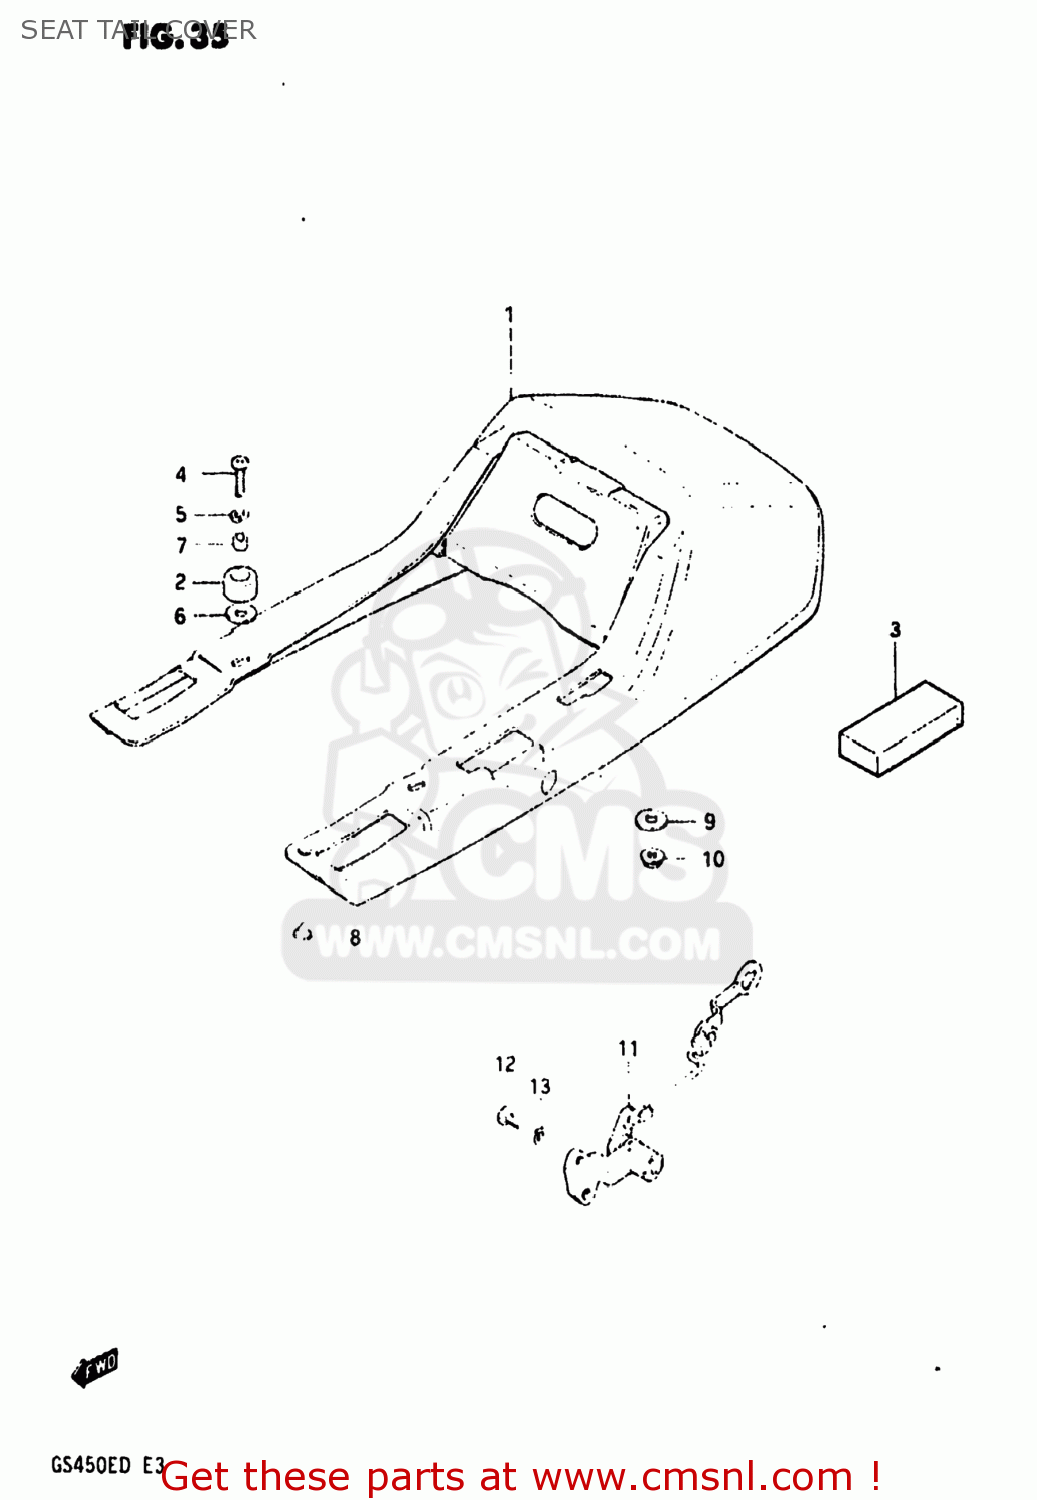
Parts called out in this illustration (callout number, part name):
1	COVER,SEAT TAIL
2	CUSHION,COVER
3	CUSHION
4	SCREW
5	LOCK WASHER
6	WASHER (6.5X24X1.6)
7	SPACER
8	CUSHION
9	WASHER
10	NUT 6MM
11	LOCK ASSEMBLY,SEAT
12	BOLT
13	LOCK WASHER
